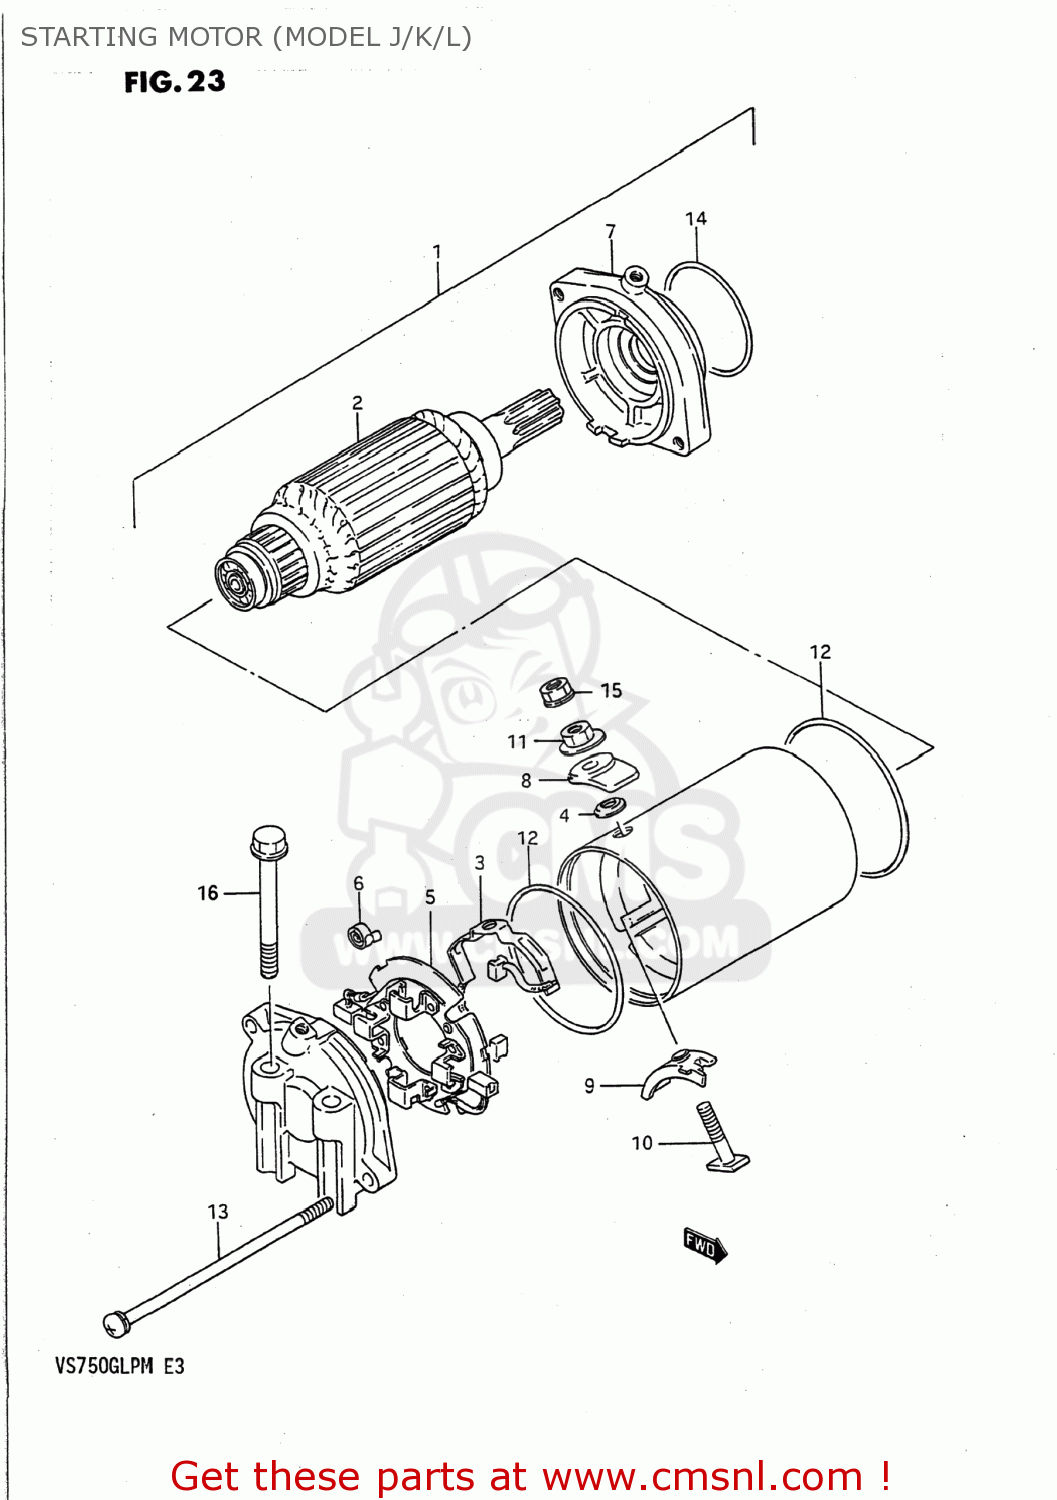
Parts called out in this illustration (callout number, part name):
1	MOTOR ASSEMBLY,STARTING
2	ARMATURE
3	TERMINAL SET,BRUSH
4	GASKET (NAS)
5	HOLDER SET,BRUSH (-)
6	SPRING
7	BRACKET SET
8	BUSHING
9	BUSHING
10	BOLT
11	NUT
12	O RING
13	BOLT
14	O RING
15	NUT
16	BOLT
